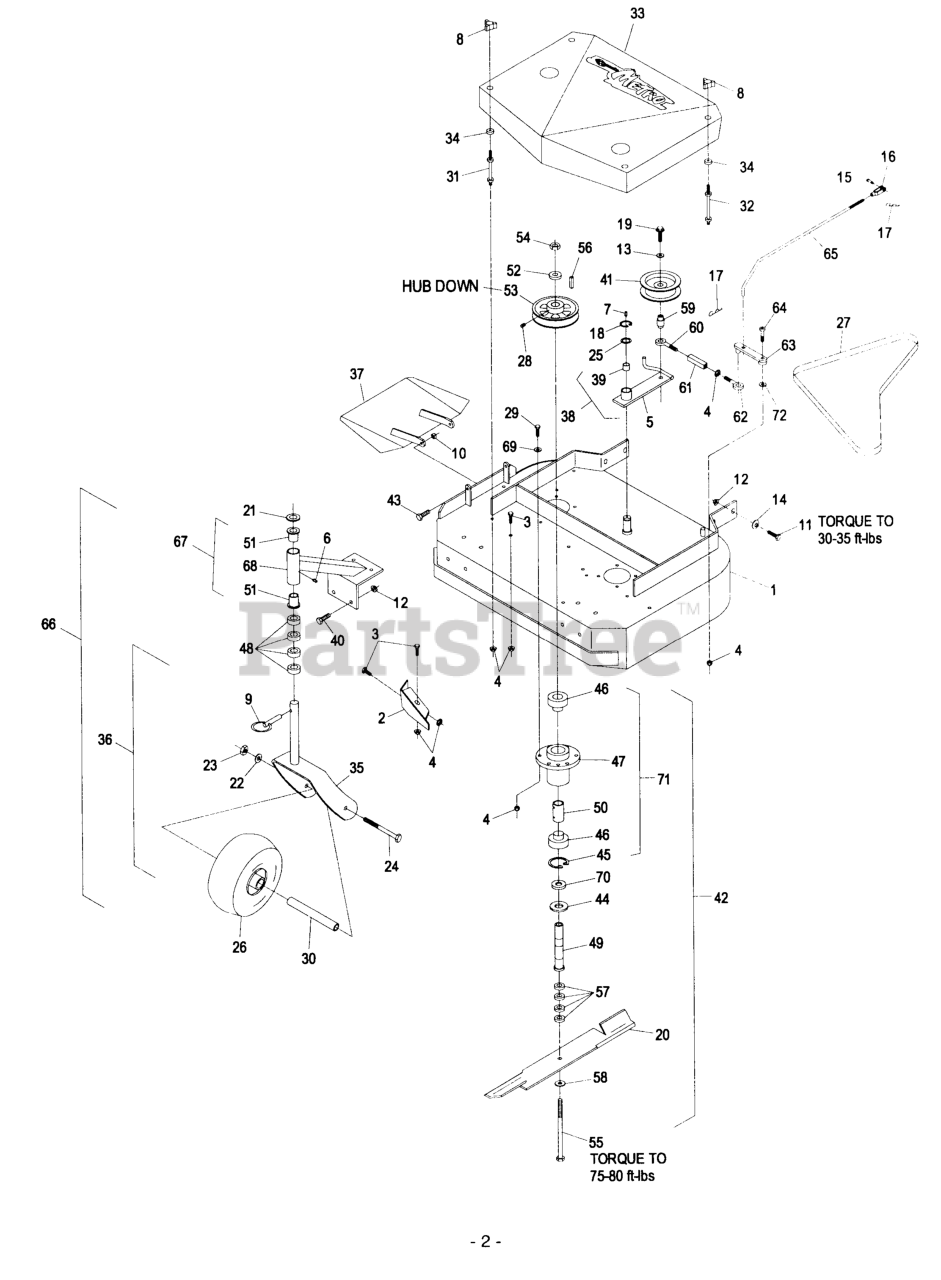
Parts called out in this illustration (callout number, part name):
2	BAFFLE-DOGLEG
8	KNOB-3 PRONG
15	PIN-CLEVIS
16	YOKE-ADJUSTABLE
17	PIN-COTTER
21	WASHER-FLAT
25	WASHER-SPINDLE
27	BELT,BLADE DRIVE
28	SCREW-SET
31	STUD-SHIELD, BELT (SHORT)
32	STUD-SHIELD, BELT (LONG)
37	WLD,CHUTE 36 RIGID
39	BEARING,POWDERED METAL
42	HOUSING,CUTTER COMPLETE(S
44	GUARD-BEARING, BOTTOM
46	BEARING
48	SPACER-CASTER
49	TUBE-SPINDLE, SHORT
50	SPACER-BEARING
51	BEARING-FLANGED
52	WASHER-RETAINER, SHEAVE
55	SCREW-CAP, HH
58	WASHER-SPRING
59	BUSHING-ENGAGEMENT
60	EYEBOLT-THREAD, LH
61	BODY-TURNBUCKLE
62	EYEBOLT-THREAD, RH
64	BOLT,SHLDR KSKH 3/8 X 1
65	ARM-ASSIST, LINKAGE
66	CASTER/MOUNT ASM
67	SUPPORT ASM
69	WASHER-SPRING
70	SPACER-PULLEY/BEARING
